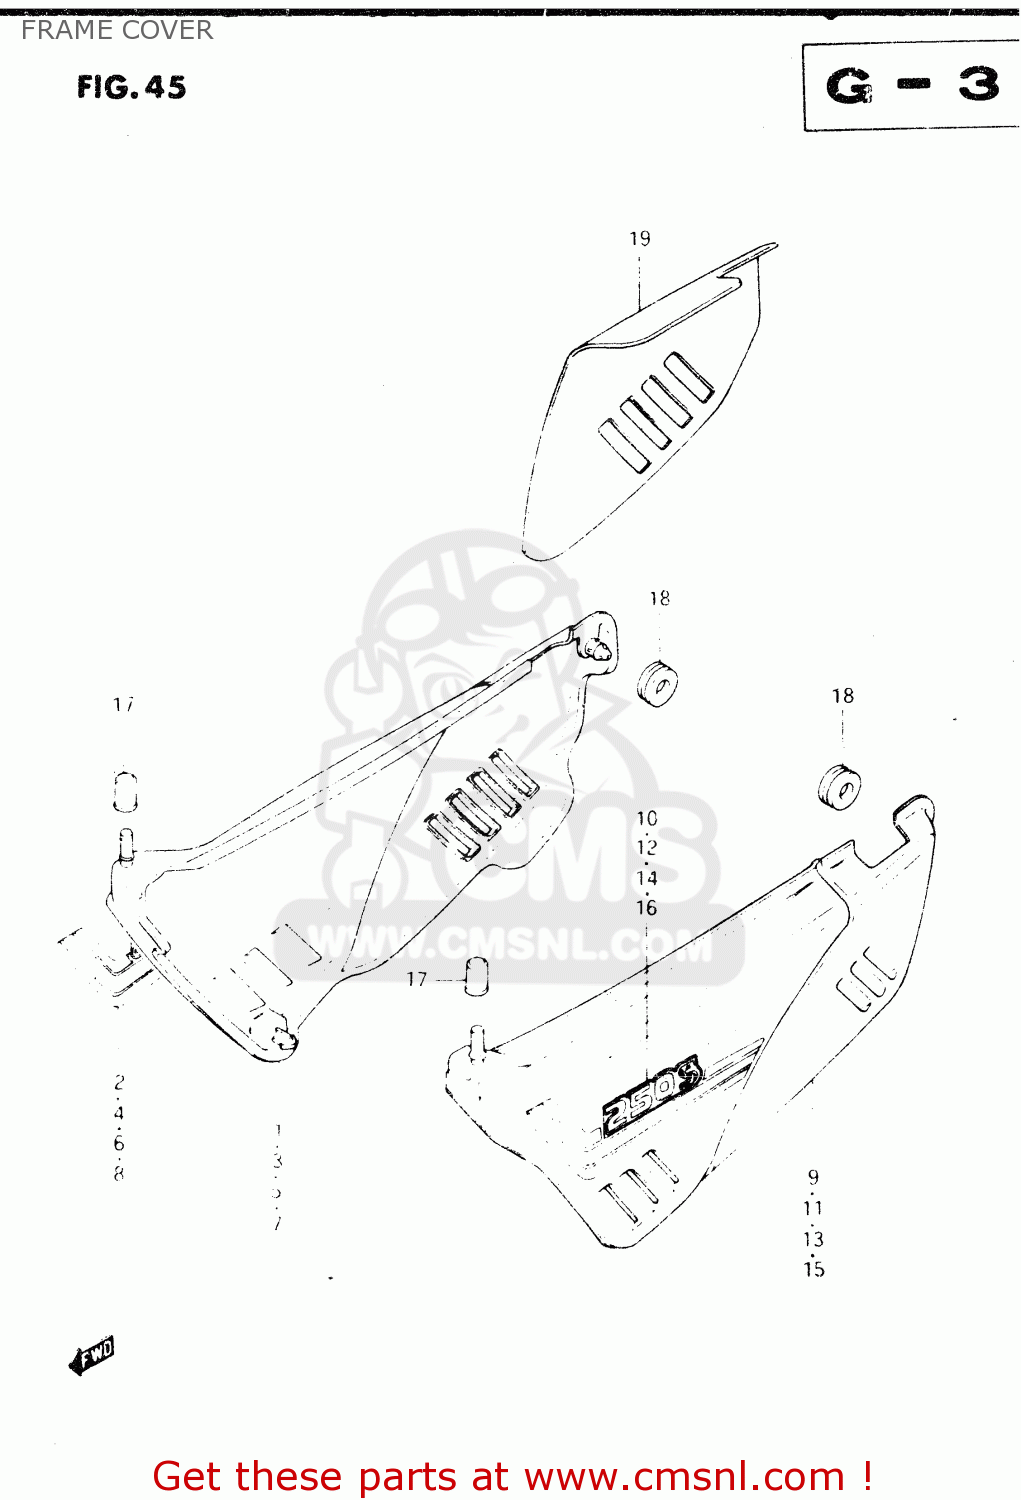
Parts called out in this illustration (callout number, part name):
1	COVER, FRAME RH (BLACK)
2	TAPE, RH
3	COVER, FRAME RH (BLUE)
4	TAPE, RH
5	COVER, FRAME RH (YELLOW)
6	TAPE, RH
7	COVER,FRAME,RIGHT
8	TAPE, RH
9	COVER, FRAME LH (BLACK)
10	TAPE, LH
11	COVER, FRAME LH (BLUE)
12	TAPE, LH
13	COVER, FRAME LH (YELLOW)
14	TAPE, LH
15	COVER,FRAME,LEFT
16	TAPE, LH
17	CUSHION
18	CUSHION
19	HEAT SHIELD,FRAME COVER
